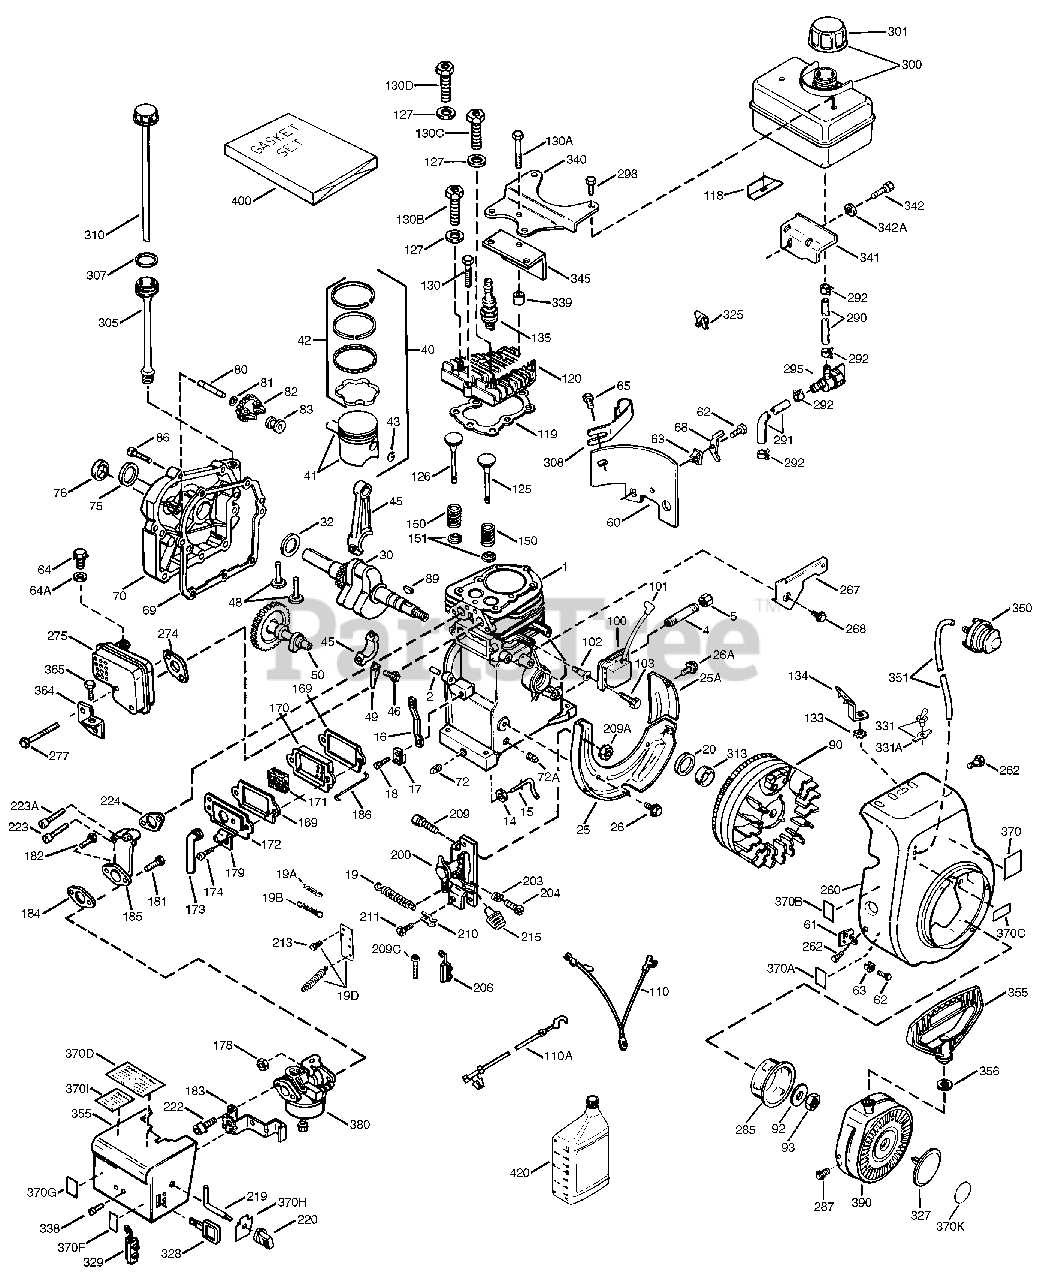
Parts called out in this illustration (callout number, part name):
1	"Cylinder (Incl. 2,20,72 & 125)
2	Dowel Pin
14	Flat Washer
15	Governor Rod
16	Governor Lever
17	Governor Lever Clamp
18	Screw, 8-32 x 5/16"
20	Oil Seal
25	Blower Housing Baffle (Incl. 262)
25A	Baffle Extension
26	Screw, 1/4-20 x 5/8"
26A	Screw, 8-32 x 21/64"
30	Crankshaft
40	Piston, Pin & Ring Set (Std.)
40	Piston, Pin & Ring Set (.010" OS)
40	Piston, Pin & Ring Set (.020" OS)
41	Piston & Pin Ass'y. (Std.) (Incl. 43)
41	Piston & Pin Ass'y. (.010" OS) Incl. 43
41	Piston & Pin Ass'y. (.020" OS) Incl. 43
42	Ring Set (Std.)
42	Ring Set (.010" OS)
42	Ring Set (.020" OS)
43	Piston Pin Retaining Ring
45	Connecting Rod Ass'y. (Incl. 46 & 49)
46	Connecting Rod Bolt
48	Valve Lifter
49	Oil Dipper
50	Camshaft (BCR)
60	Blower Housing Extension
62	Screw, 8-32 x 3/8"
63	Breather Tube Grommet
65	Screw, 10-24 x 1/2"
68	Ground Terminal
69	* Cylinder Cover Gasket
70	Cylinder Cover Incl. 75 thru 86, 311 & 312
72	Oil Drain Plug (Sq. hd., 1/4-18)
72A	Oil Drain Plug (Sq. hd., 1/4-18)
75	Oil Seal
80	Governor Shaft
82	Governor Gear Ass'y. (Incl. 81)
83	Governor Spool
86	Screw, 1/4-20 x 1-1/4"
89	Flywheel Key (also available in Packa ged Part #740007B)
90	Flywheel
92	Belleville Washer
93	Flywheel Nut
100	Solid State Ignition
101	Spark Plug Cover
102	Solid State Mounting Stud
103	Screw, Torx T-15, 10-24 x 15/16"
110	Ground Wire
119	* Cylinder Head Gasket
120	Cylinder Head (Incl. 131)
125	Exhaust Valve (Std.) (Incl. 151)
125	Exhaust Valve (1/32" OS) (Incl. 151)
126	Intake Valve (Std.) (Incl. 151)
126	Intake Valve (1/32" OS) (Incl. 151)
130	Screw, 5/16-18 x 1-1/2"
131	Screw, 5/16-18 x 2"
133	Lock Washer, 5/16
134	Shorting Clip
135	Resistor Spark Plug - RJ17LM
150	Valve Spring
151	Valve Spring Cap
169	* Valve Cover Gasket
170	Breather Body
171	Breather Element
172	Valve Cover
173	Breather Tube
174	Screw, 10-24 x 9/16"
178	Nut & Lock Washer 1/4-28
181	Screw, 1/4-28 x 1-11/16"
182	Screw, 1/4-28 x 7/8"
184	* Carburetor To Intake Pipe Gasket
185	Intake Pipe
186	Governor Link
223	Screw, 1/4-20 x 1-3/8"
223A	Screw, 1/4-20 x 1-19/32"
224	* Intake Pipe Gasket
260	Blower Housing
262	Screw, 1/4-20 x 1/2"
267	Hold Down Bracket
268	Screw, 10-24 x 9/16"
285	Starter Cup
287	Screw, 8-32 x 21/64"
290	Fuel Line
292	Fuel Line Clamp
298	Screw, 1/4-15 x 7/8"
300	Fuel Tank (Incl. 292 & 301) (2 Quart)
301	Fuel Cap (Red)
327	Starter Plug
340	Fuel Tank Bracket
342	Screw, 1/4-20 x 7/16"
345	Heat Baffle
370A	Lubrication Decal
380	Carburetor (Incl. 184)
390	Rewind Starter NOTE: This engine cou ld have been built with 590688 starte r. Refer to the design of the air int ake louvers for part identification. Individual starter parts do not inter change.
400	* Gasket Set (Incl. items marked PK in notes) Incl. part #'s 26756 (1), 2723 4A (2), 27272A (1), 27677A (1), 29673 (1), 33670A (1), 33673A (1), 36443 ( 1)
